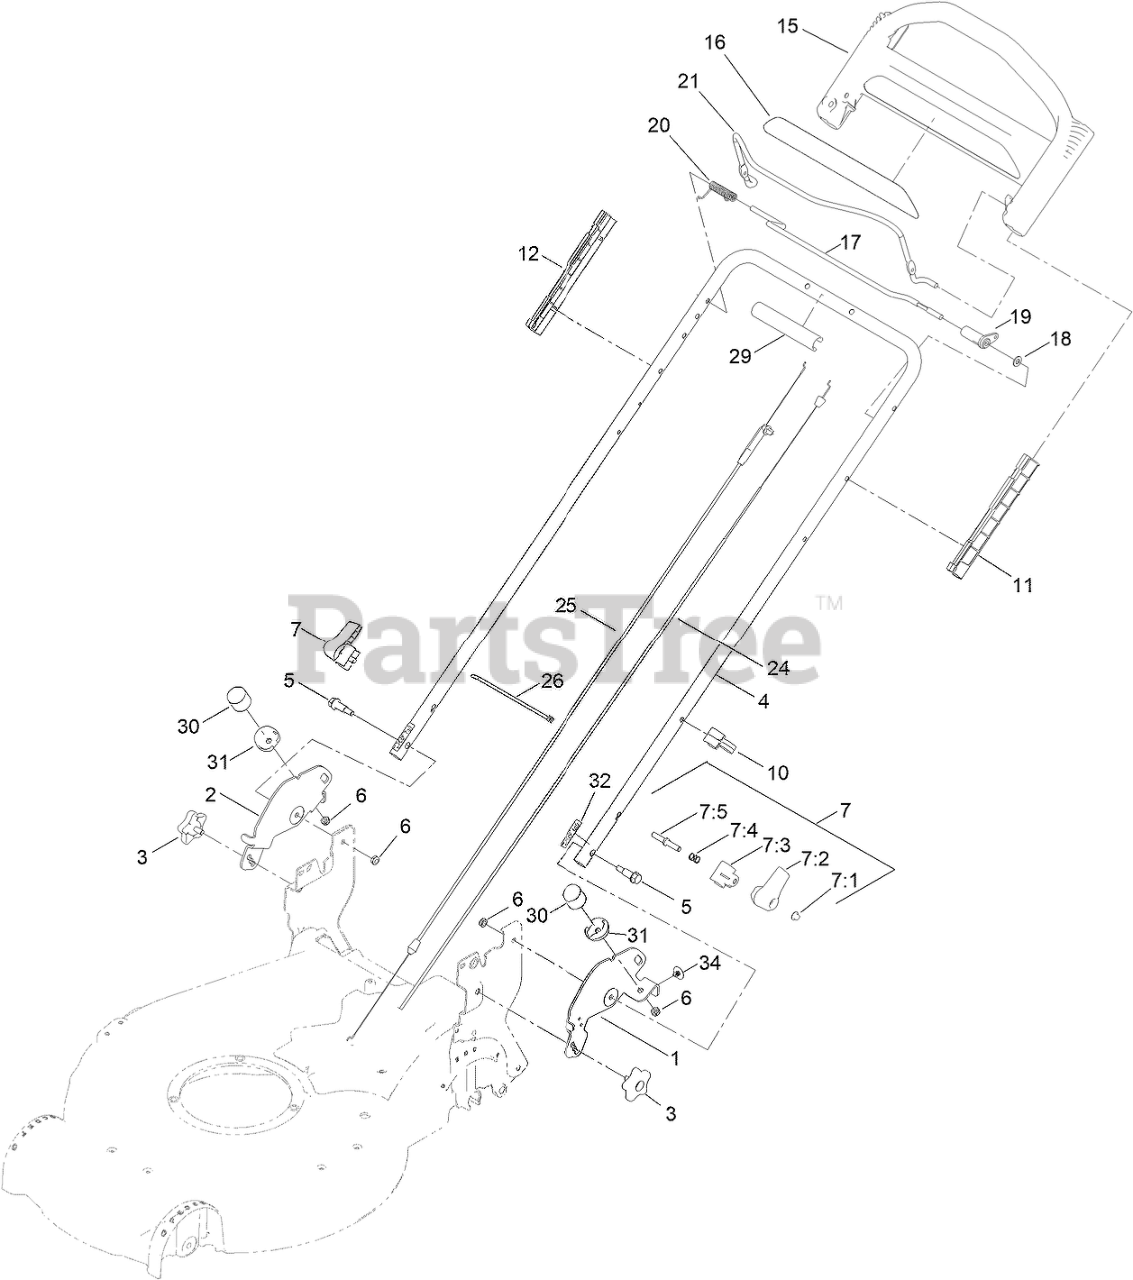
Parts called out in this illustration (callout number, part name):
1	BRACKET-FLOAT, LH
2	BRACKET-FLOAT, RH
3	KNOB-HANDLE
4	HANDLE-UPPER
5	BOLT-SHOULDER
6	NUT-LOCK, NI
7	QUICK RELEASE ASM
7:1	NUT-PUSH
7:2	LEVER-RELEASE
7:3	ANCHOR-SPRING
7:4	SPRING-COMPRESSION
7:5	ROD-RELEASE
10	GUIDE-CABLE
11	GUIDE-LH
12	GUIDE-RH
15	HANDLE-CONTROL
17	BAR-CONTROL, TRACTION
18	WASHER-PLAIN
19	LEVER-TRACTION
20	SPRING-TORSION
21	BAIL-BRAKE
24	CABLE-TRACTION
25	CABLE-BRAKE
26	TIE-CABLE
29	HANDLE-COVER
30	BUMPER-RUBBER
31	COVER-BUMPER
32	DECAL-FLEX
34	CLIP-TREE
